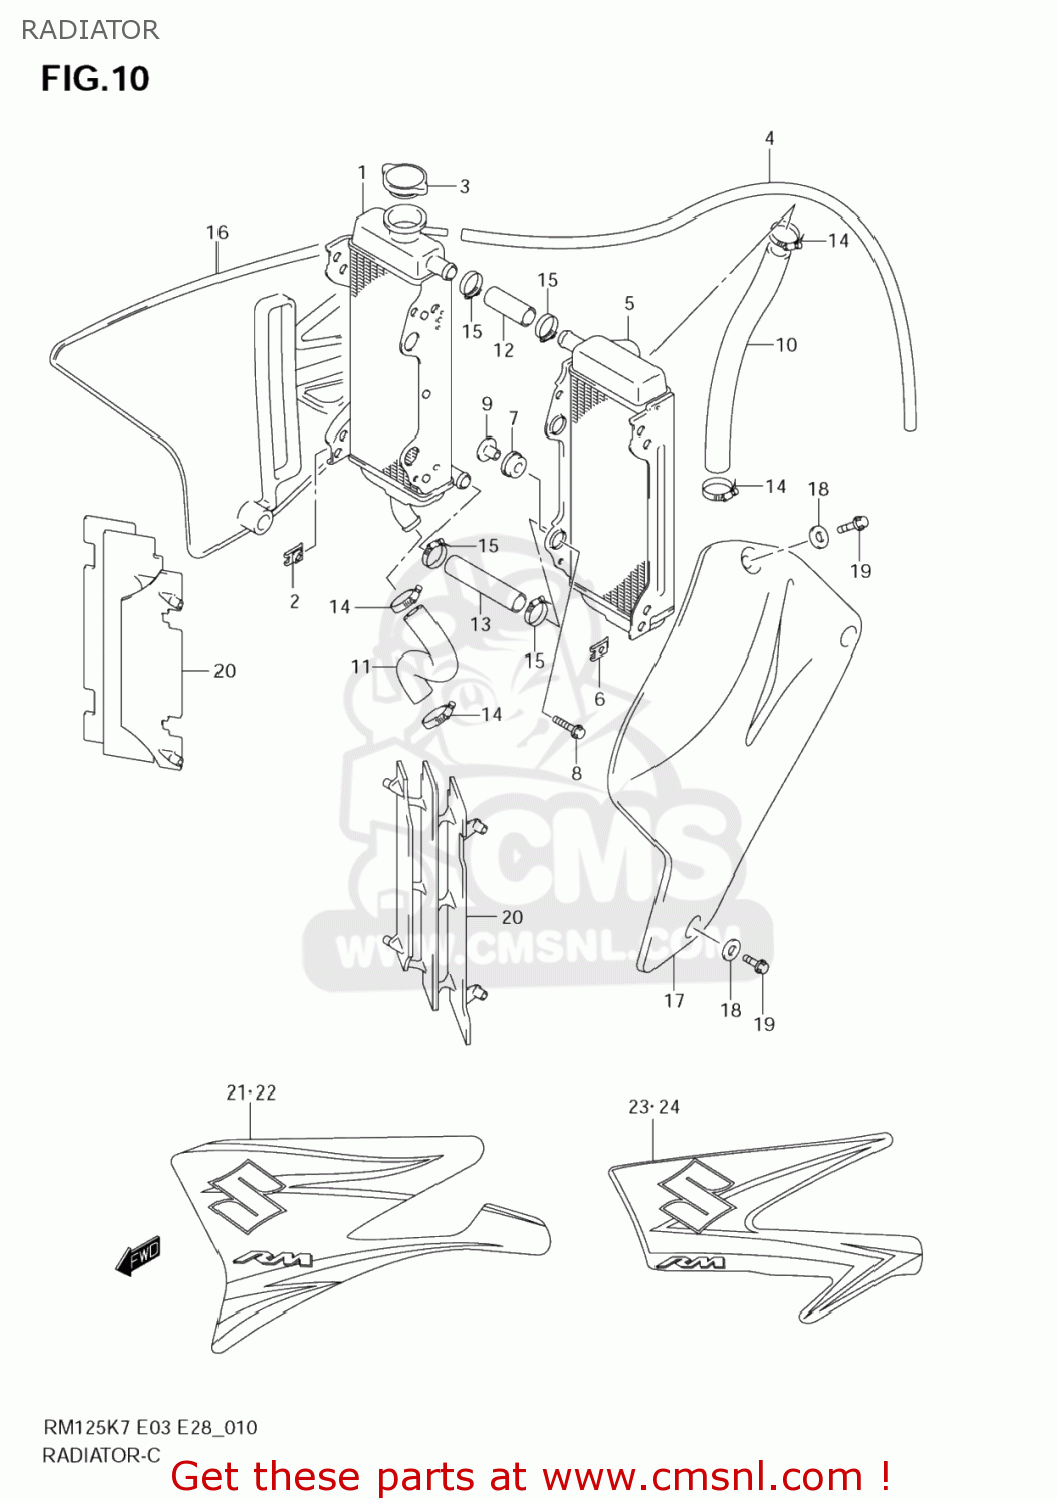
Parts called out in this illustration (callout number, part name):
1	RADIATOR,WATER,R
2	NUT
3	CAP COMP,RADIATOR
4	HOSE(5X8X1000)
5	RADIATOR,WATER,L
6	NUT
7	CUSHION,RADIATOR LWR
8	BOLT(6X25)
9	SPACER(6.5X10.5X14.1)
10	HOSE,RADIATOR INLET
11	HOSE,RADIATOR OUTLET
12	HOSE,RADIATOR JOINT
13	HOSE,RADIATOR JOINT
14	CLAMP
15	CLAMP
16	COVER,RADIATOR,R(YELLOW)
17	COVER,RADIATOR,L(YELLOW)
18	WASHER,RR BRAK
19	BOLT(6X12)
20	LOUVER,RADIATOR
21	TAPE,RADIATOR COVER,R
22	TAPE,RADIATOR COVER,L
23	TAPE,RADIATOR COVER,R
24	TAPE,RADIATOR COVER,L
